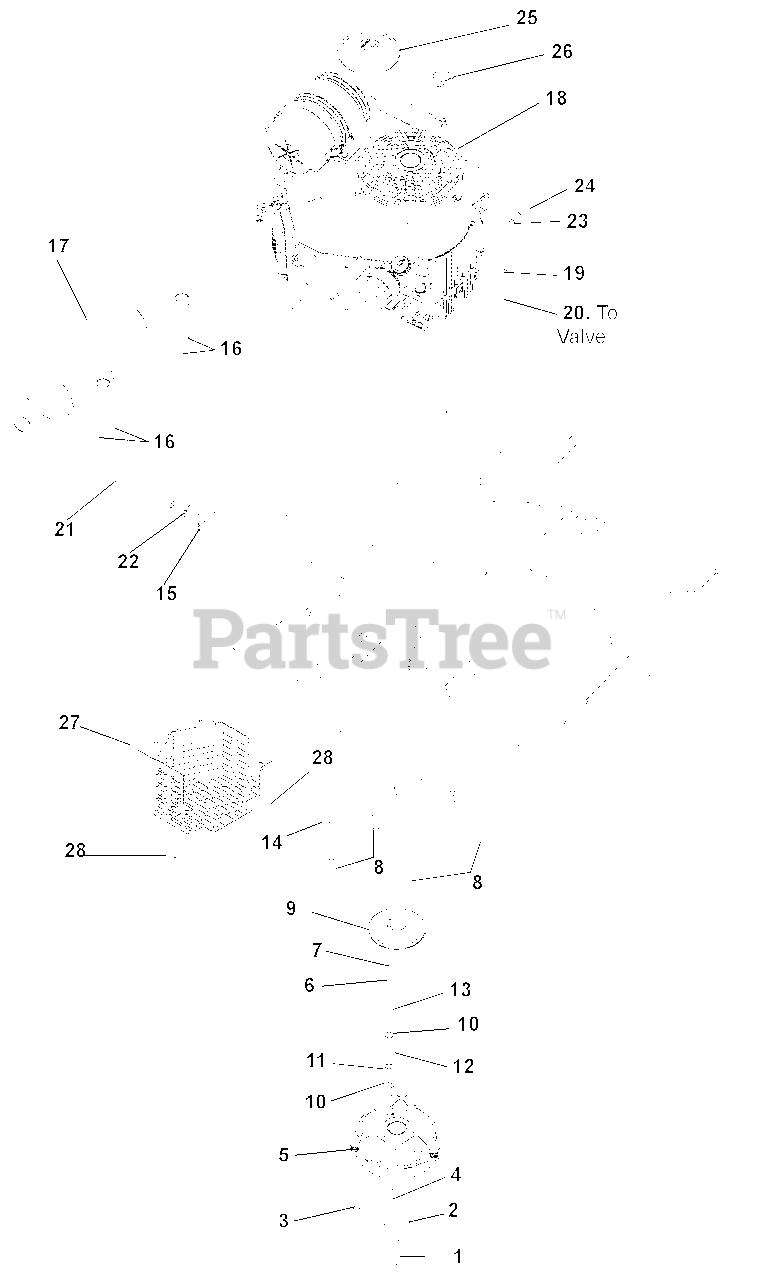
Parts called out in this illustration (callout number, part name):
1	Bolt, Hex .44-20 x 2.50
2	Washer, Flat-Steel .469 x 2.00 x .25
3	Nut, Locking-Top-Flange .38-16
4	Key .25 x .25 x 2.25
5	Clutch, Ogura GT2.5-FE02
6	Spacer, 1.125 x 1.50 x 1.40
7	Key, Square .25 x .625 x .25 SAE 8630 or SAE 1035
8	Bolt, Hex .38-16 x 1.25 FTH EP80
9	Pulley, 4.50 OD x 1.127 Engine
10	Washer, Flat-Steel .406 x .812 x .065
11	Bushing, Sleeve .407 x .625 x .813 Steel
12	Bumper, Rubber .62 x 1.0 x .88 LG Engine
13	Bolt, Hex .38-16 x 1.50
14	100I Clutch Stop Weldment
15	Drain, .50 Oil
16	Nut, Locking-Top M8-1.25
17	Muffler, Kawasaki Fixed
18	Engine, Kawasaki FX691
19	Clamp, Fuel Line
20	Hose, .25 Low-Perm Bulk Gas
21	Tube, Oil Drain 8" Clear Vinyl
22	Clamp, .88 Diameter Hose
23	Washer, Locking .31 x .078 Regular
24	Bolt, Hex M8-1.25 x 20
25	Cap, Air Cleaner Rain
26	Clamp, Hose 2.75 Dia. Worm
27	Weldment, Clutch and Belt Guard
28	Screw, Tapping .38-16 x .50 Hex Washer Head
